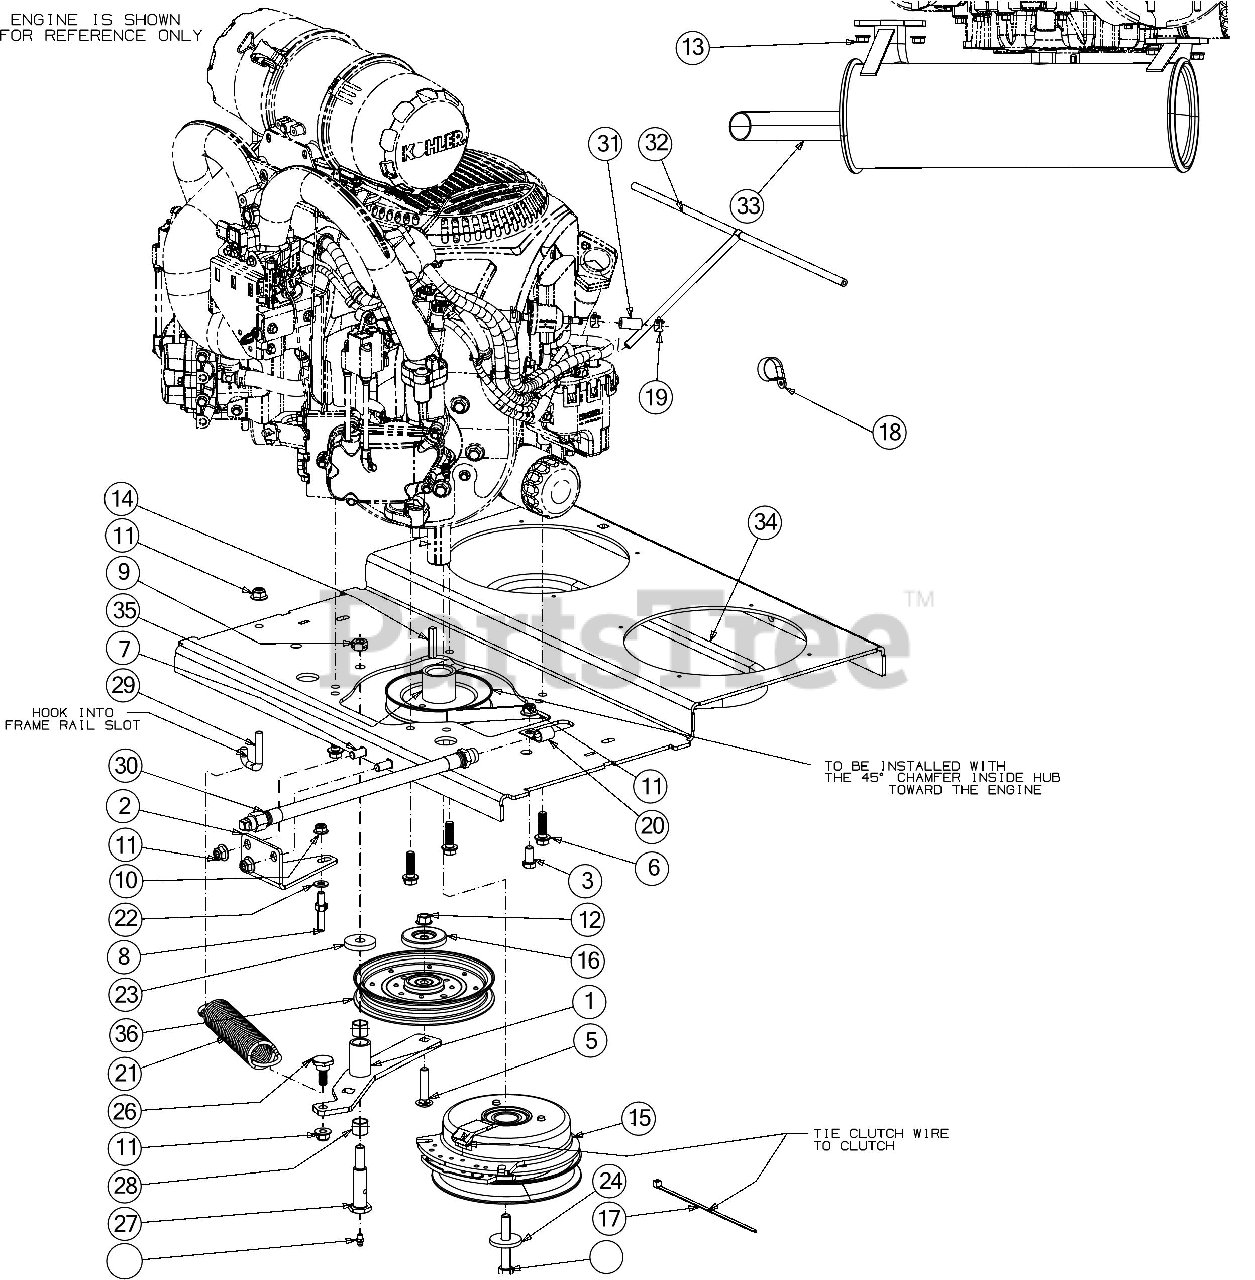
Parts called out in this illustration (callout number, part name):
1	TRANSMISSION IDLER BRACKET
2	RETAINER BRACKET
3	HEX SCREW 3/8-16 x .75
4	SCREW 7/16-20:2.75 GR5
5	CARRIAGE BOLT 3/8-16 x 1.75 GR5
6	SCREW 3/8-16 x 1.25 GR5
7	CARRIAGE BOLT 3/8-16 x 1.00 GR5
10	FLANGE LOCK NUT 5/16-18
12	HEX LOCK NUT
13	HEX FLANGE NUT
14	SQUARE KEY 1/4 x 1.50
15	ELECTRIC PTO CLUTCH
16	PULLEY CAP
17	7" CABLE TIE
18	DRAIN HOSE CLAMP
20	J TYPE CLIP
21	EXTENSION SPRING
22	FLAT WASHER
23	FLAT WASHER 47 x 1.50 x .225
24	FLAT WASHER .45 x 1.5 x .172 HT
25	GREASE FITTING
26	SHOULDER SCREW .625 x .302 x 3/8-16
27	SHOULDER BOLT 7/16-14
28	SLEEVE BEARING
29	ROD SPRING HOOK
30	OIL DRAIN HOSE
31	FUEL HOSE LOW PERMEATION
32	ROLLOVER VENT HOSE ASSEMBLY
34	TRANSMISSION BELT
35	DRIVE PULLEY
36	IDLER PULLEY
